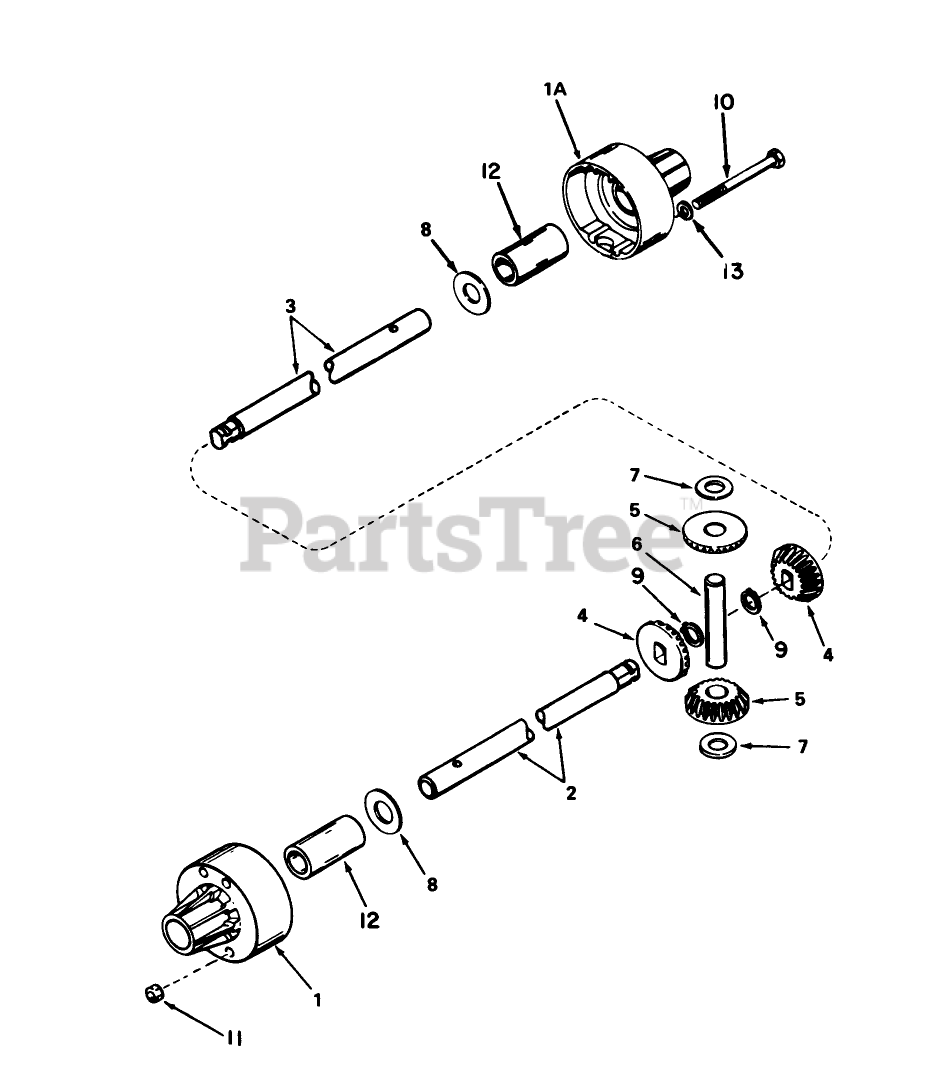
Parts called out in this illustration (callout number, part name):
1	Housing, Differential Carrier (Incl. Ref. #13)
1A	Housing, Differential Carrier (Incl. Ref. #13)
2	Axle(10-1/4" long)
3	Axle (18-7/8" long)
4	Bevel Gear
5	Gear Pinion
6	Pin Drive
7	Washer Thrust
8	Washer
9	Ring-Snap
10	Screw-Hex Hd.
11	Nut-Lock
12	Bushing
13	Washer
